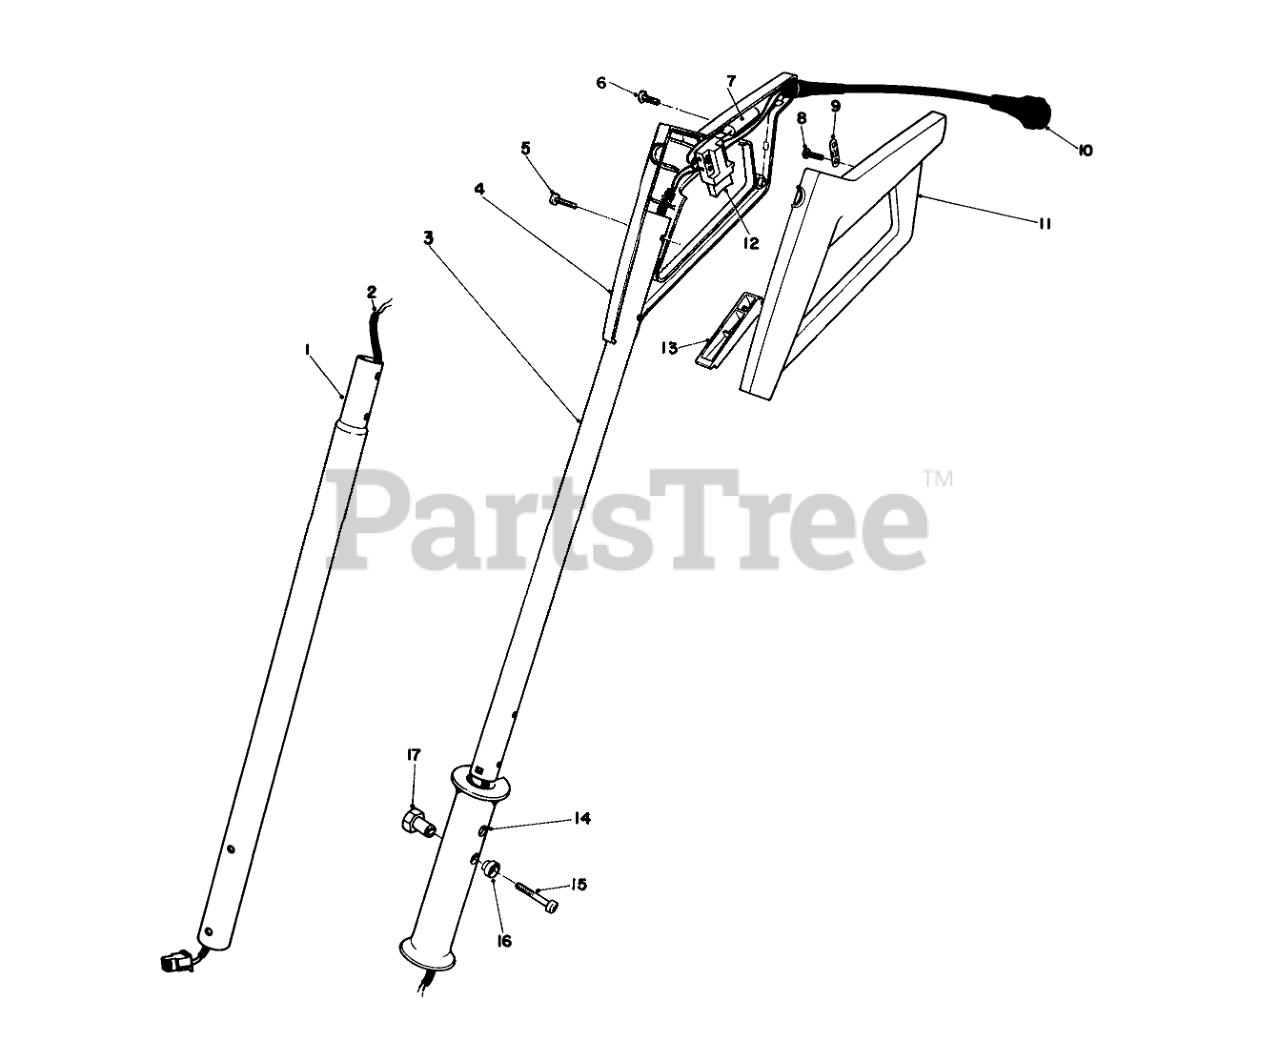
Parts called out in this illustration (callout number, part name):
1	LOWER TUBE, P. SHOVEL
2	Wire Harness
3	Tube-Upper Handle
4	RH GRIP
5	Screw
6	SCREW-PPH
7	CAPACITOR
8	Screw, Pan Head
9	Clamp-Power Cord
10	Power Cord-Upper Wiring Harness
11	LH GRIP
12	Switch
13	Switch Bar
14	Grip-Handle
15	SPEC PAN HD SCREW
16	Bushing-Screw
17	SPECIAL HEX NUT
